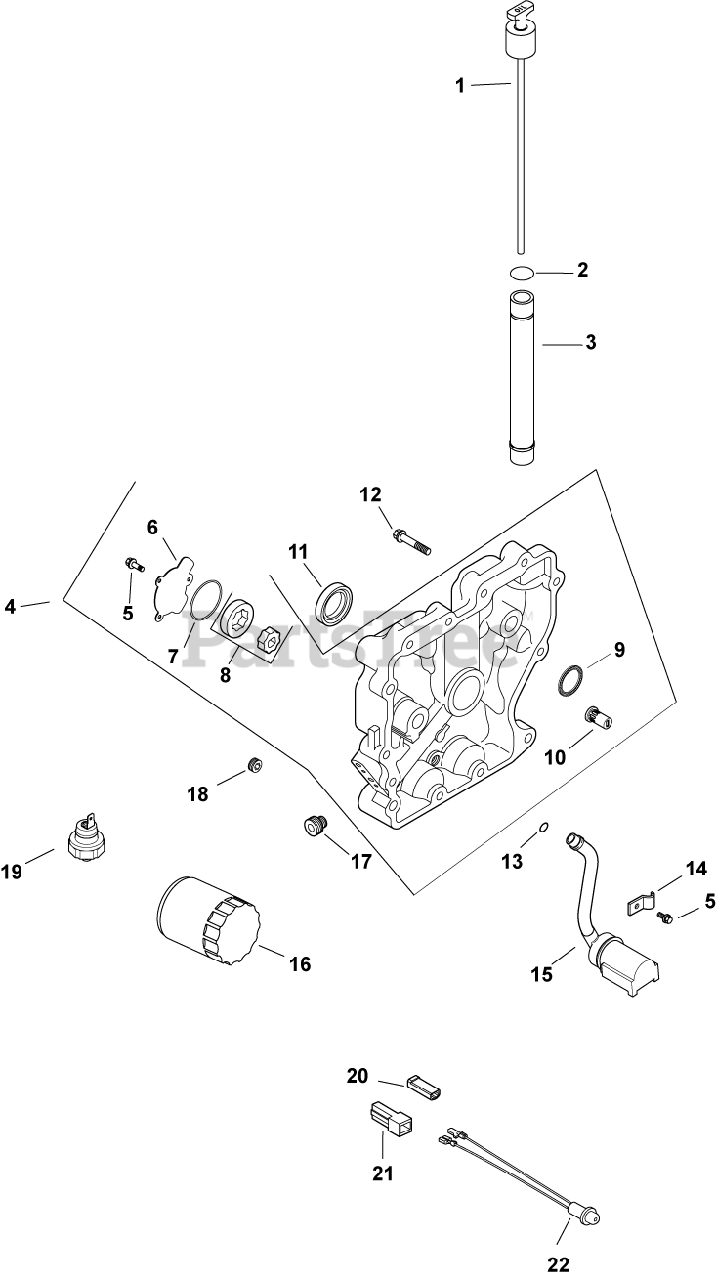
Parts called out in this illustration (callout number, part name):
3	KIT, OIL FILL TUBE - METAL
4	CLOSURE PLATE ASSEMBLY
5	SCREW,FLG THD FRM M5X0.8X16-(#25086398S)
6	COVER, OIL PUMP
7	O-RING (1.78" DIA)
8	PUMP ASSEMBLY, OIL
9	BEARING, CRANKSHAFT
10	VALVE, OIL PRESSURE RELIEF
11	SEAL, OIL
12	SCREW, FLG M8X1.25X45
13	O-RING (.5" DIA)
15	KIT, OIL PICK-UP
16	OIL FILTER
17	NIPPLE, OIL FILTER
18	PLUG, CTSK PIPE 1/8"
19	SENSOR, OIL PSI
20	CONNECTOR (1 CONTACT)
21	CONNECTOR
